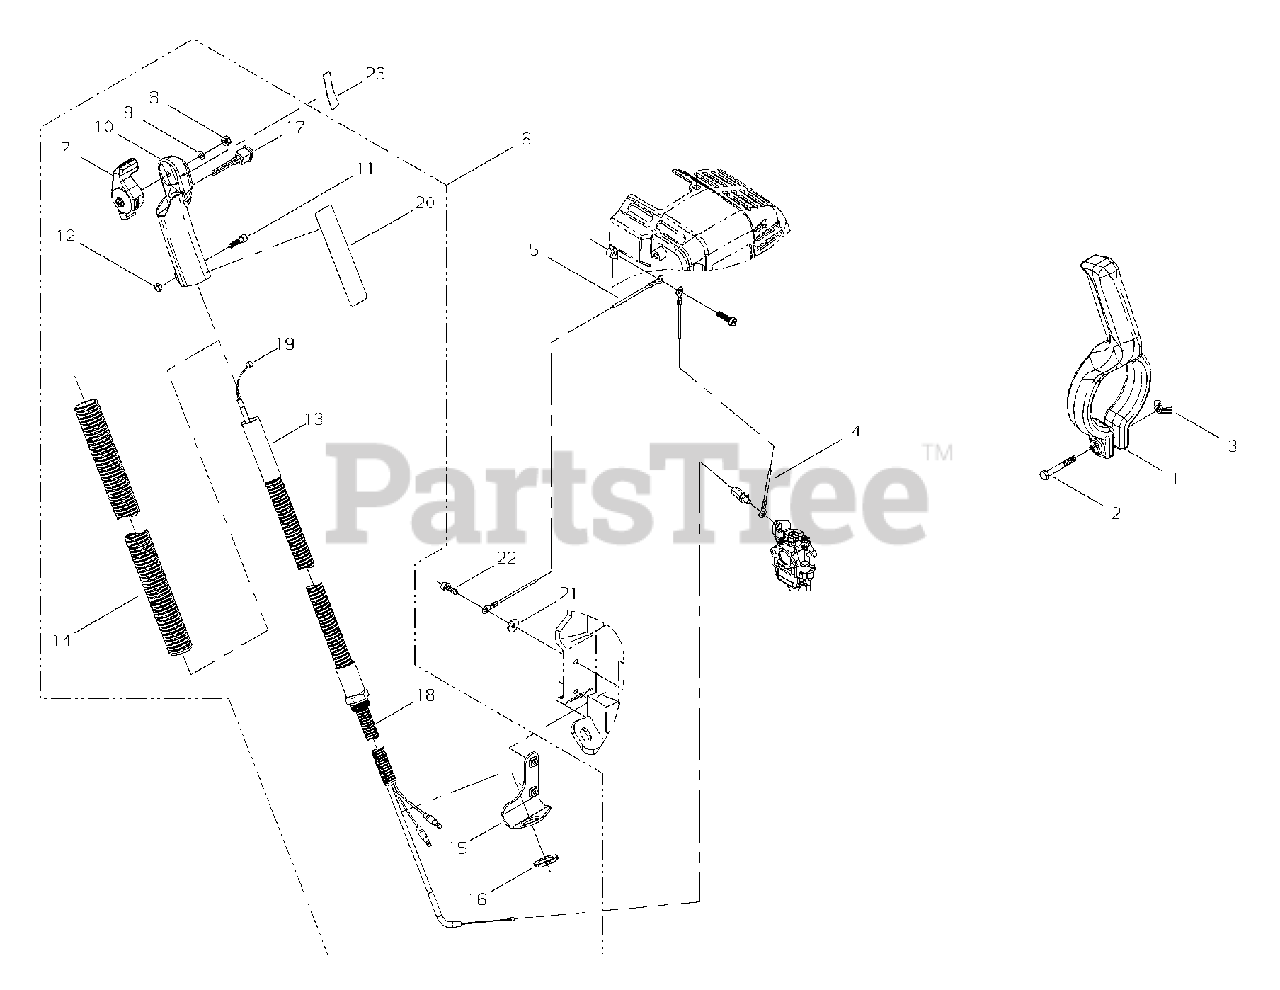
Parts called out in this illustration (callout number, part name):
1	HANDLE
2	BOLT - 6X45
3	WINGNUT
4	LEAD - ANTI-STATIC - 110mm
5	LEAD - GROUND
6	THROTTLE ASSY
7	THROTTLE LEVER ASSY
8	NUT - 5
9	WASHER - 5
10	GRIP
11	SCREW - 5X20
12	NUT - 5
13	FLEX ARM
14	TUBE, PROTECTIVE
15	BRACKET, MOUNTING
16	NUT - 21
17	IGNITION SWITCH ASSY
18	FLEX TUBE
19	CABLE, THROTTLE
20	PLATE - GROUND
21	COLLAR
22	SCREW - 5X18
23	LABEL - INSTRUCTION
